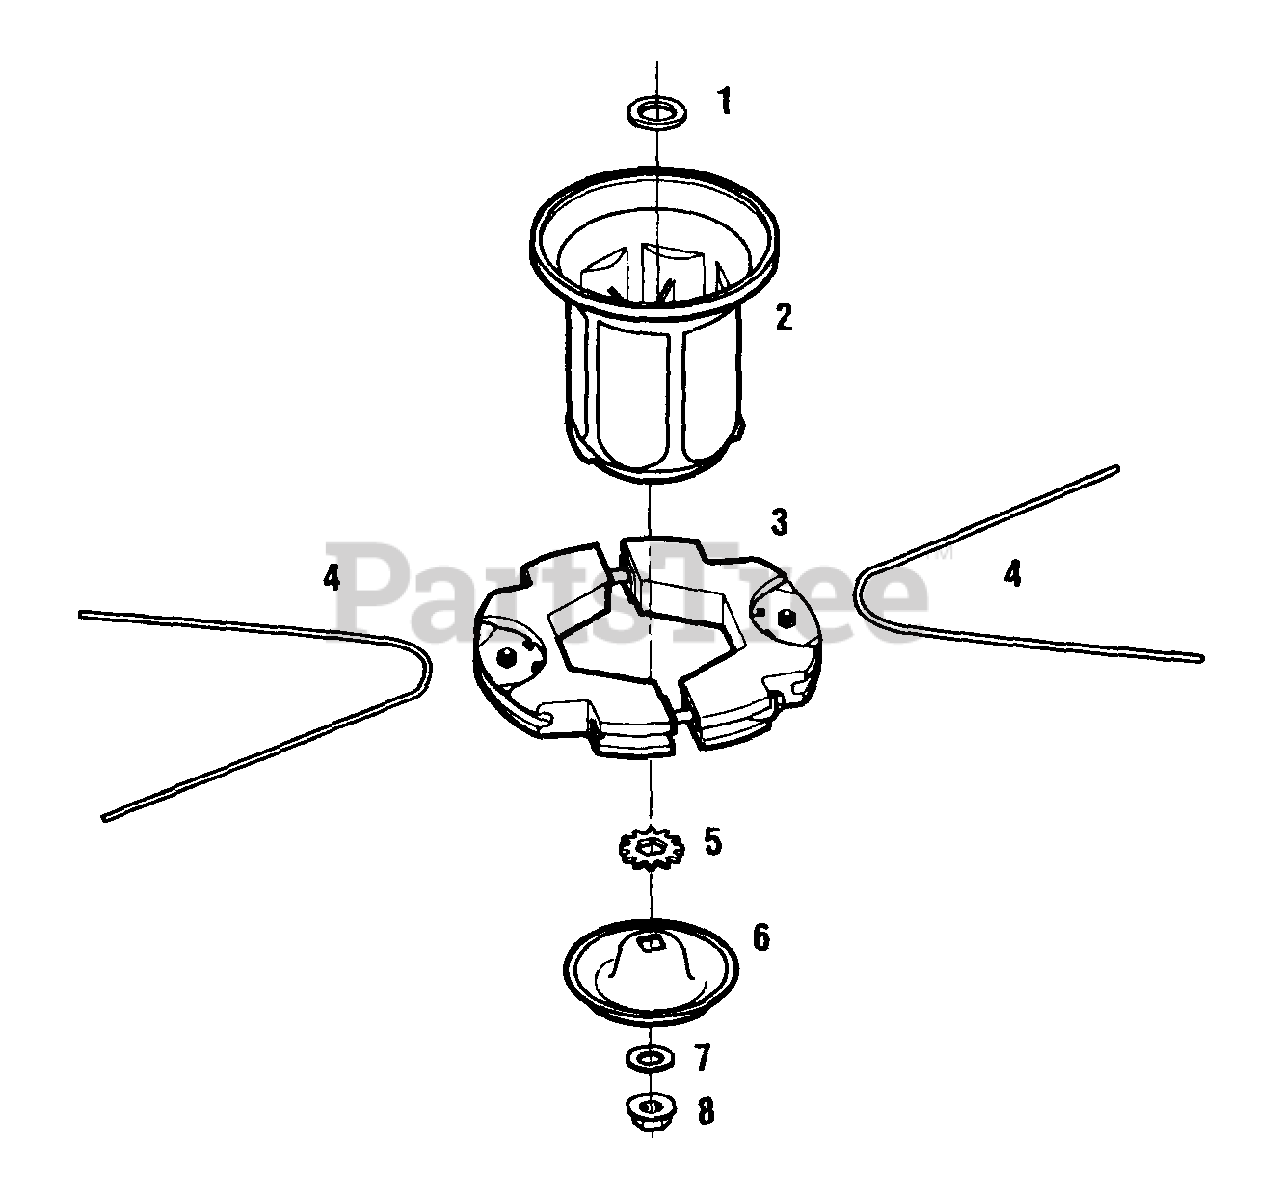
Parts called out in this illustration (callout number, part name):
1	Shoulder Washer
2	Spindle Head
3	Trimmer Head
4	Trimmer String
5	Hex Spline Washer
6	Wear Cup
7	Washer
8	Hex Flange Nut, 1/2-13
